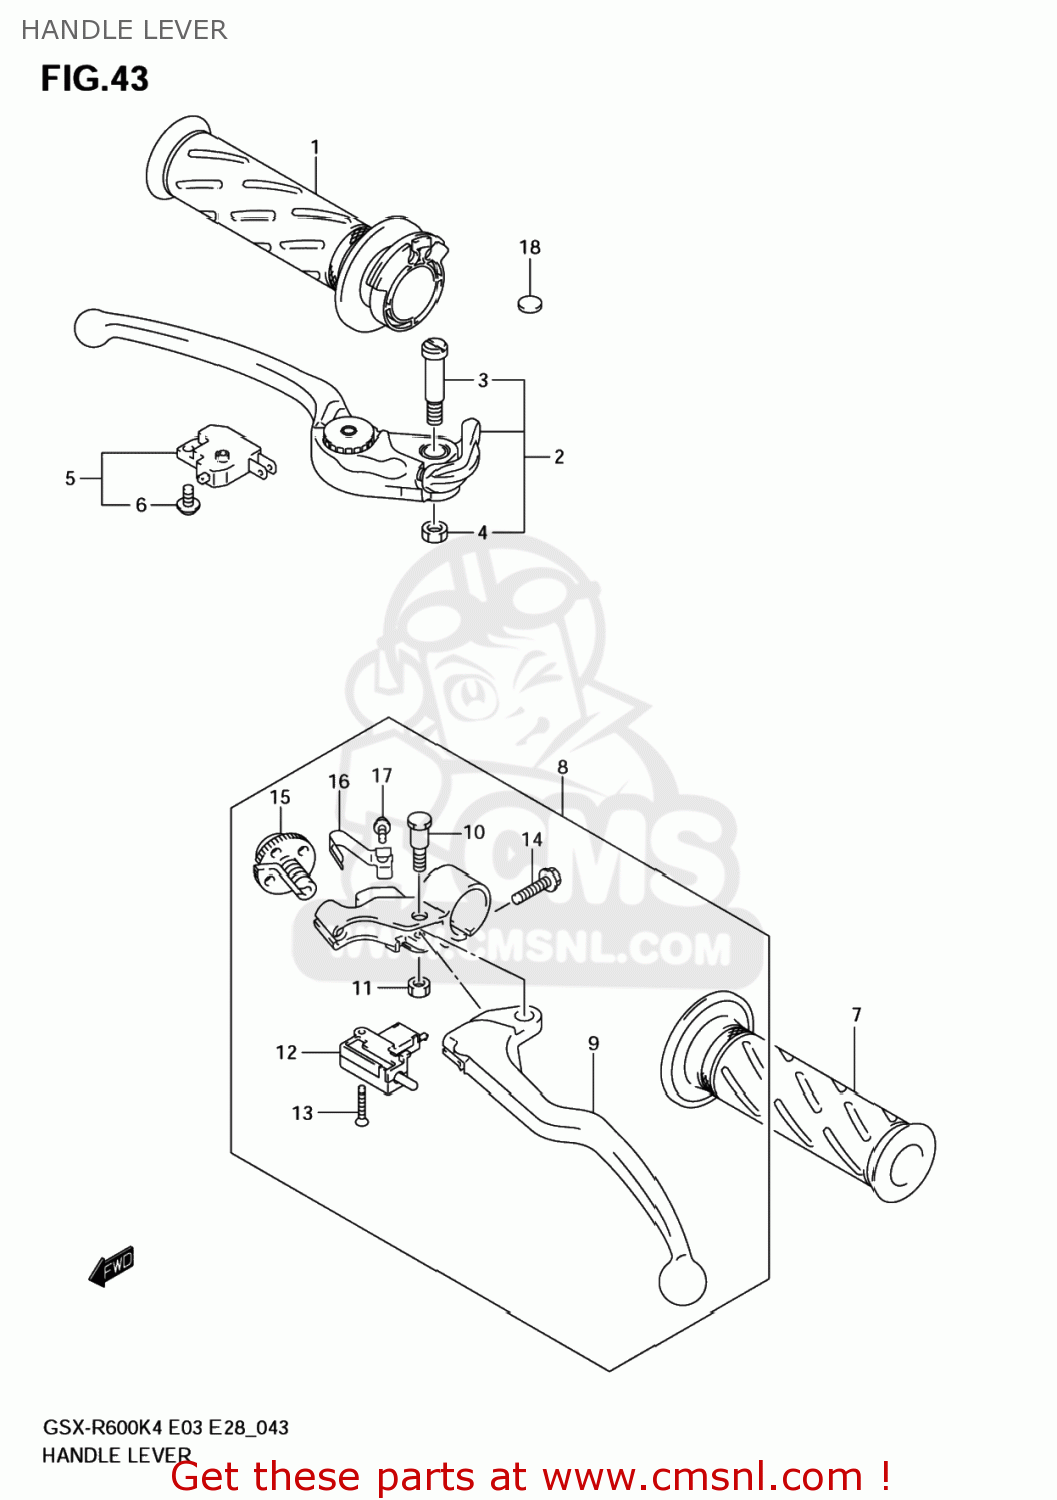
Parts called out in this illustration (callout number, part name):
1	GRIP COMP,THRO
2	LEVER ASSY,BRA
3	BOLT,LEVER PIVOT
4	NUT,LEVER PIVOT
5	SWITCH ASSY,ST
6	SCREW
7	GRIP,LEFT
8	LEVER ASSY,CLU
9	LEVER,CLUTCH
10	BOLT,LEVER PIVOT
11	NUT
12	SWITCH,CLUTCH
13	SCREW
14	SCREW
15	NUT,CABLE ADJUSTER
16	SPRING,ADJUST
17	SCREW,SPRING
18	RUBBER,MASTER CYLINDER
